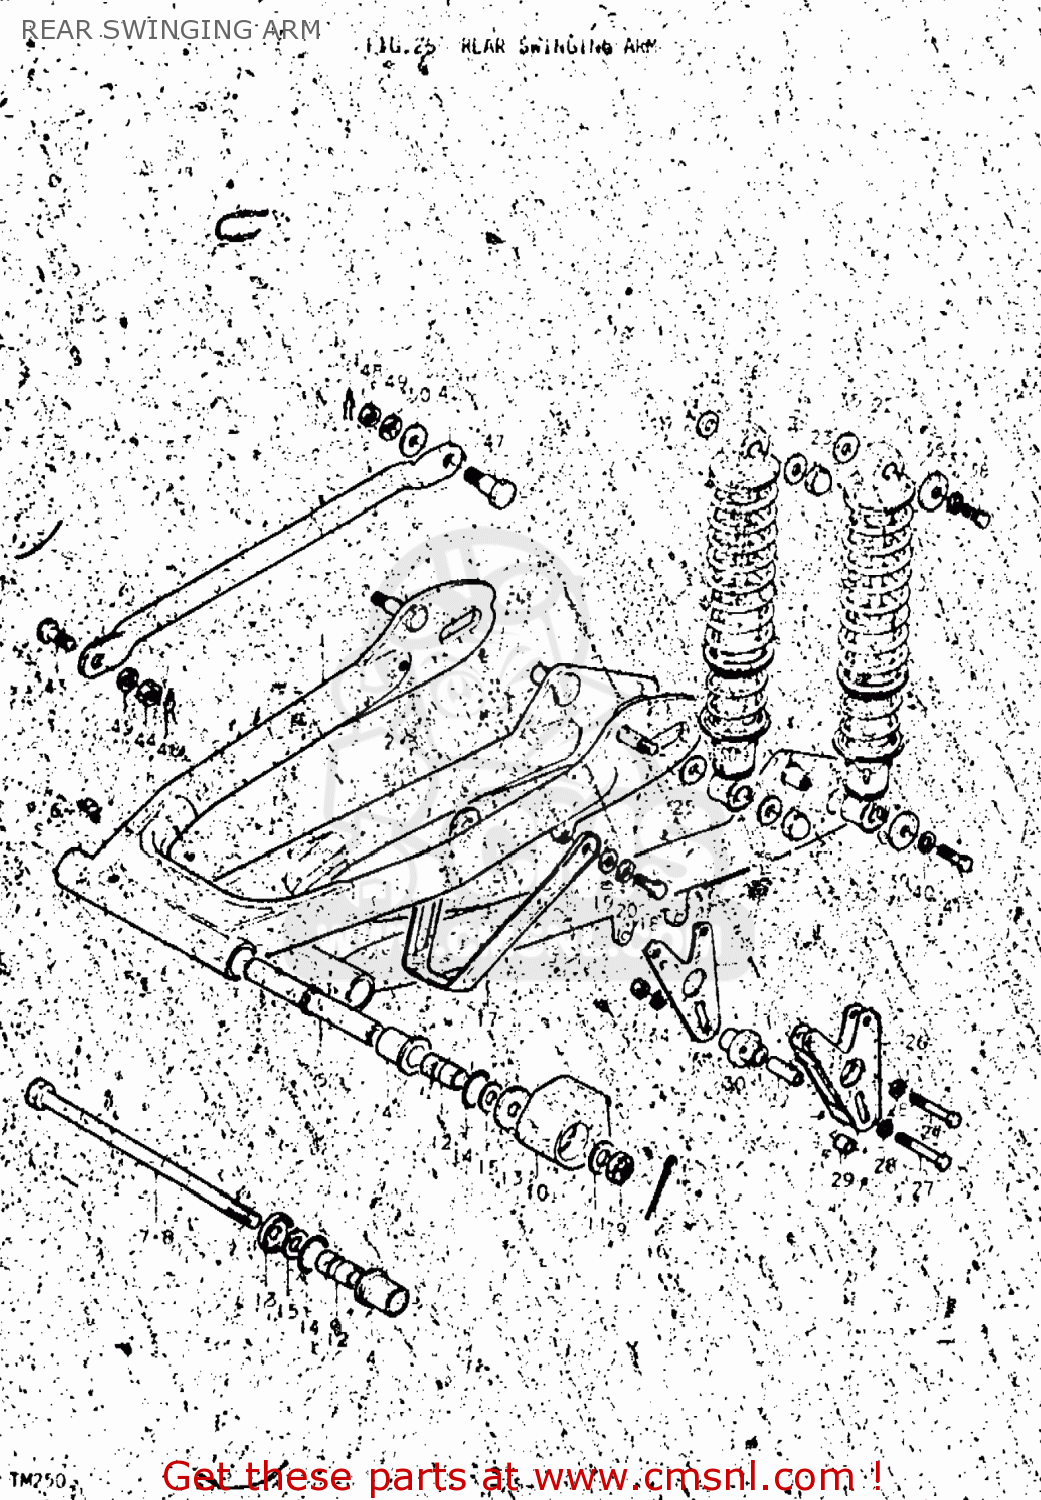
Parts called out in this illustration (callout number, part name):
1	SWING ARM ASSEMBLY,REAR
2	SWING ARM ASSEMBLY,REAR
3	SWING ARM ASSEMBLY,REAR
4	BUSHING
5	SPACER,SWING ARM,CENTER
6	NIPPLE,GREASE
7	SHAFT,REAR SWING ARM
8	SHAFT,REAR SWING ARM
9	NUT
10	BUFFER,CHAIN TOUCH DEFLECTOR
11	WASHER
12	SPACER,REAR SWING ARM
13	COVER
14	O RING(D:2,ID:24.5)
15	WASHER(12.5X24X2.3)
16	COTTER PIN
17	GUIDE,CHAIN
18	BOLT
19	WASHER 6MM
20	LOCK WASHER
21	ABSORBER ASSEMBLY,REAR SHOCK
22	ABSORBER ASSEMBLY,REAR SHOCK
23	NUT
24	WASHER
25	WASHER
27	BOLT
28	LOCK WASHER
29	SPACER(6.5X12X6.9)
30	ROLLER,CHAIN GUIDE
31	NUT (6MM)
32	SPACER
33	TENSIONER,CHAIN
34	WASHER
35	WASHER
36	WASHER (6.5X24X1.6)
37	LOCK WASHER
38	BOLT
39	WASHER
40	LOCK WASHER
41	BOLT
42	TORQUE LINK,REAR
43	BOLT(8X22.5)
44	NUT
45	LOCK WASHER
46	CLIP
47	BOLT
48	NUT
49	LOCK WASHER
50	WASHER (12.5X24X1.6)
51	CLIP
